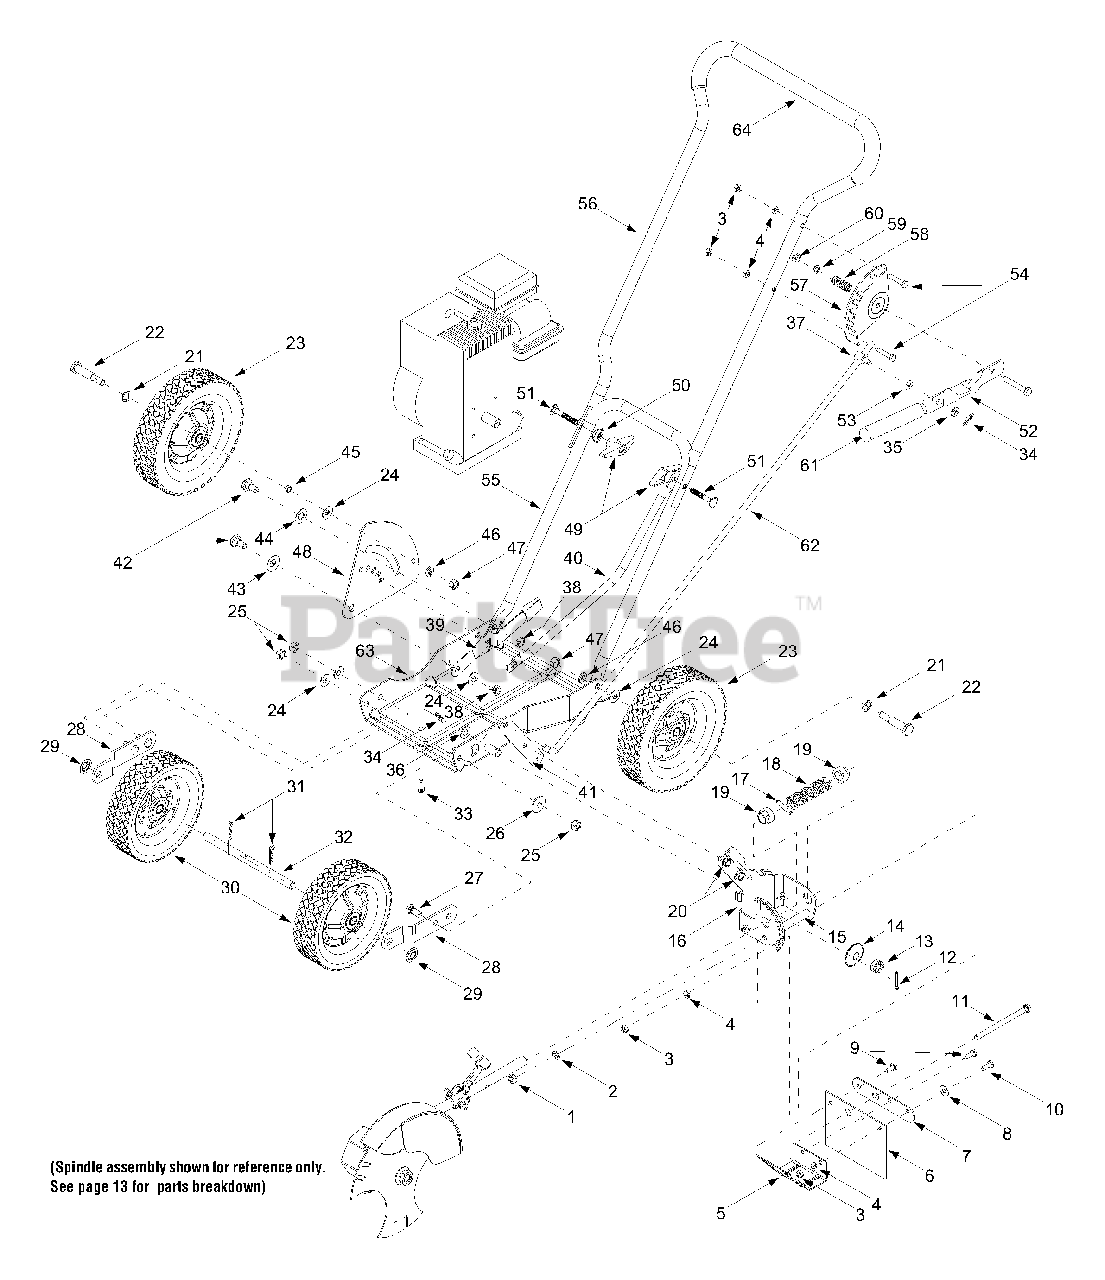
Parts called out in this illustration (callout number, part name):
1	Hex Nut, 5/16-18
2	Lock Washer, 5/16
3	Hex Nut, 1/4-20
4	Lock Washer, 1/4
7	Flap Bracket, 1.12 x 5.5
8	Flat Washer, .283 x .75 x .030
9	Hex Screw w/ Nose, 1/4-20 x .85
10	Hex Screw, 1/4-20 x .62
11	Hex Screw, 5/16-18 x 4.5
12	Cotter Pin, 1/8 x 1.0
13	Slotted Hex Nut, 1/2-20
14	Sphere Washer, .531 x 1.6 x .045
15	Spacer, .38 x .50 x 3.75
18	Compression Spring
19	Shoulder Spacer, .635 x .620
20	Self-tapping Screw, 5/16-18 x .50
21	Wave Washer, .510 x .75 x .017
22	Shoulder Screw, .498 x 1.45
23	Wheel w/ Ball Bearing, 8 x 1.75
24	Spring Washer, .401 x .871 x .063
25	Hex Nut, 3/8-24
26	Bell Washer, .396 x 1.14 x .095
27	Rd Hd Bolt 3/8-24 x .89
30	Wheel w/ Ball Bearing, 7 x 1.75
31	Internal Cotter Pin, .08 x 1.42
32	Front Axle, .50 x 7.98
33	Self-tapping Screw, 3/8-16 x 1.0
34	Internal Cotter Pin, .072 x 1.0
35	Flat Washer, .330 x .630 x .0635
36	Flat Washer, .406 x .810 x .051
37	Adjustment Ferrule
38	Center Lock Nut, 3/8-24
39	Curb Adjustment Lever Assembly
43	Bell Washer, .51 x 1.14 x .040
44	Flat Washer, .51 x 1.0 x .060
45	Spacer, .376 x .625 x .22
46	Lock Washer, 3/8
47	Hex Nut, 3/8-16
50	Saddle Washer, .320 x .93
51	Carriage Bolt, 5/16-18 x .75
53	Spring Washer, .317 x .625 x .099
54	Hex Cap Screw, 5/16-18 x 2.0
58	Compression Spring, .55 x 1.37
59	Flat Washer, .344 x .62 x .030
60	Hex Lock Nut, 5/16-18
61	Foam Grip (Blade Clutch Lever)
62	Clutch Rod, 3/8 x 33.5
